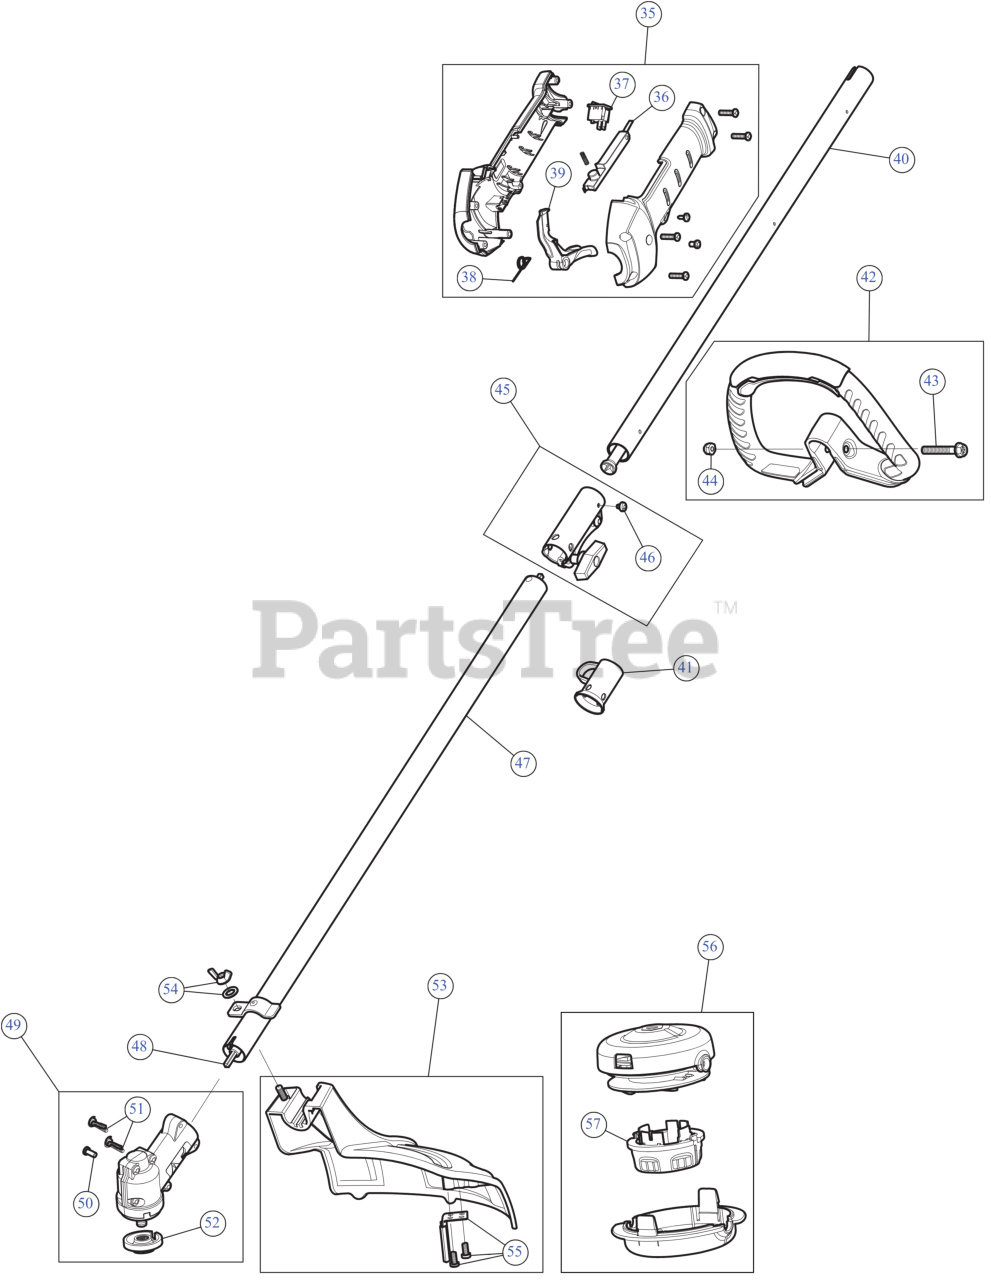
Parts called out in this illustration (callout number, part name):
35	THROTTLE GRIP ASSEMBLY
36	THROTTLE LVR LKOUT
37	SW, MOMENTARY ON/O
38	SPRING TRIG
39	THROTTLE TRIGGER
40	BOOM ASSEMBLY UPR
41	HANGER
42	HANDLE ASSEMBLY
43	BOLT 1/4-20X1 1/2
44	NYLON LOCK NUT
45	COUPLER ASSEMBLY
46	SCREW, 10-32X.250 TA
47	BOOM ASSEMBLY LOWER
48	LOWER DRIVE SHAFT
49	GEARBOX LCBC
50	SCREW, 8-32 x .312 P
51	SCREW #
52	CUTTING HEAD SPACER
53	GUARD/BLADE ASM
54	BLADE GUARD MOUNTING HARDWARE
55	BLADE ASSEMBLY W/HDW
56	CUTTING HEAD
57	WASHER
